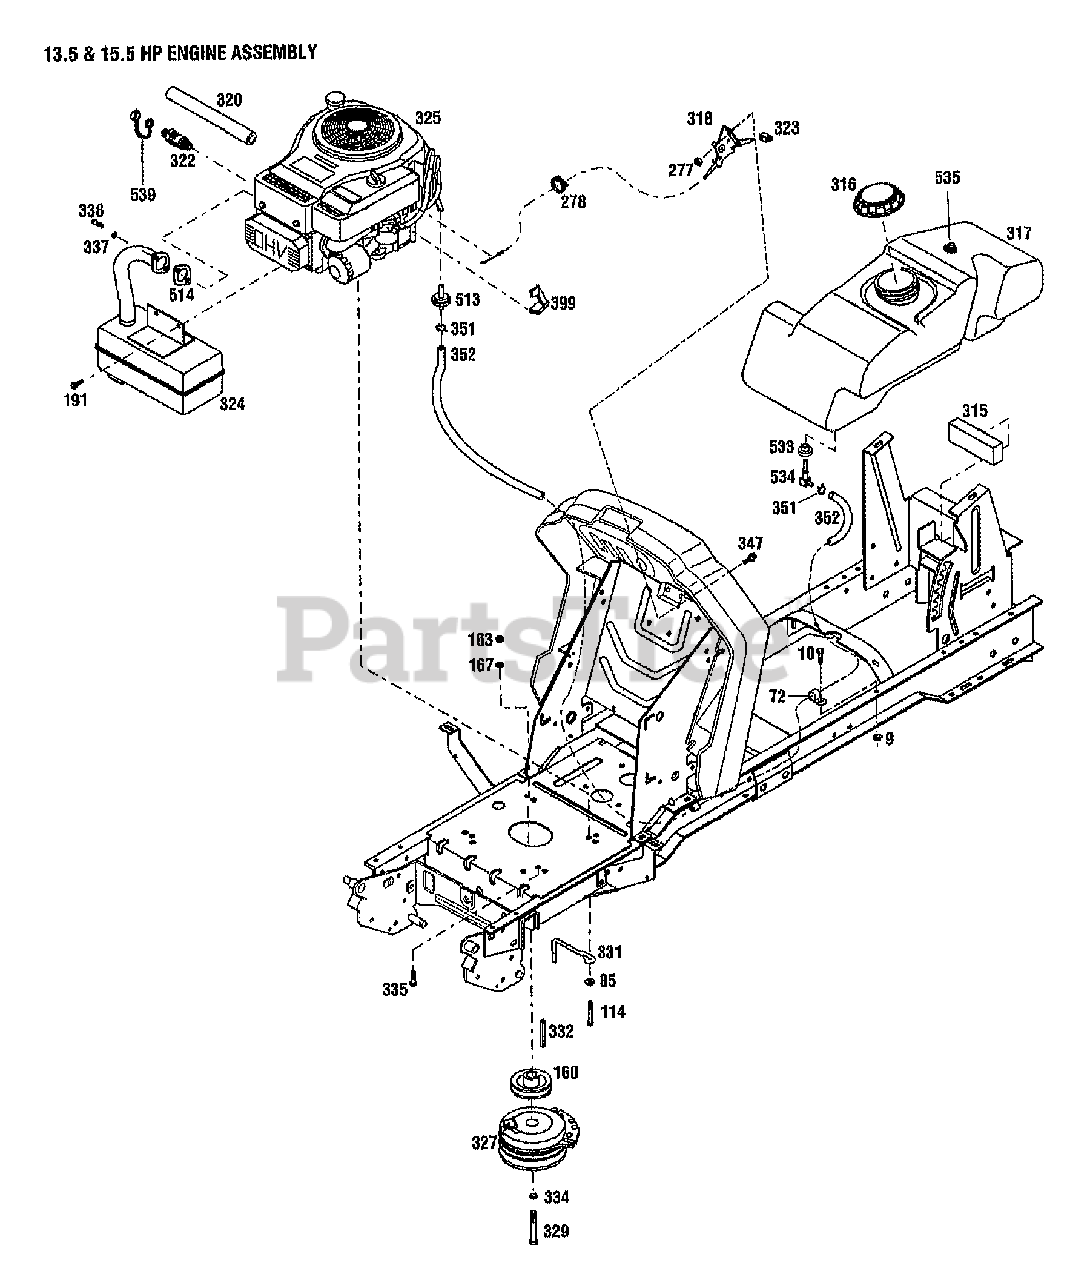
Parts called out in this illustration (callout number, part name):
9	NUT-HFLK 5/16-18 ZP
10	SCR-HHC 5/16-18X.75 GR 5 ZP
72	CLAMP-WIRE
85	WASHER-FLAT 3/8 SAE
114	SCR-THRD FRM 3/8-16X1.50
160	PULLEY-ENGINE
163	NUT-HEX 3/8-16 ZP
167	WASHER-LK .375 @ DEPL
191	SCR-FLANGE 1/4-20X3/4 GR5
277	NUT W/LKWASHER 10-24 ZP
278	TIE-CABLE NYLON BLACK
315	PAD-FUEL TANK
316	CAP-FUEL
317	TANK-FUEL
318	CONTROL-THROTTLE
320	HOSE-OIL DRAIN
322	ASSM-OIL VALVE
324	MUFFLER
325	ENGINE, 13.5HP BRIGGS & STRATTON {13103}
325	ENGINE, 15.5HP BRIGGS & STRATTON {13104}
327	CLUTCH-ELECTRIC
329	SCR-HH 7/16-20X3 G5 ZP
331	CLUTCH-RETAINER
332	KEY-.25 SQ X 1.5
334	WASHER-LK .438 ZP
335	SCR-HH 3/8-16X1.0 THDFM
337	WASHER-LOCK
338	SCR-HXSKT 5/16-18X.75 BO
347	SCR-MACH 10-24X3/4
351	CLAMP-HOSE
352	LINE-FUEL
399	CLIP-ENGINE
513	FILTER-FUEL
514	MUFFLER GASKET
533	BUSHING-RUBBER
534	ELBOW-90 DEG (FUEL LINE)
535	VENT-FUEL TANK
539	CAP-OIL DRAIN
